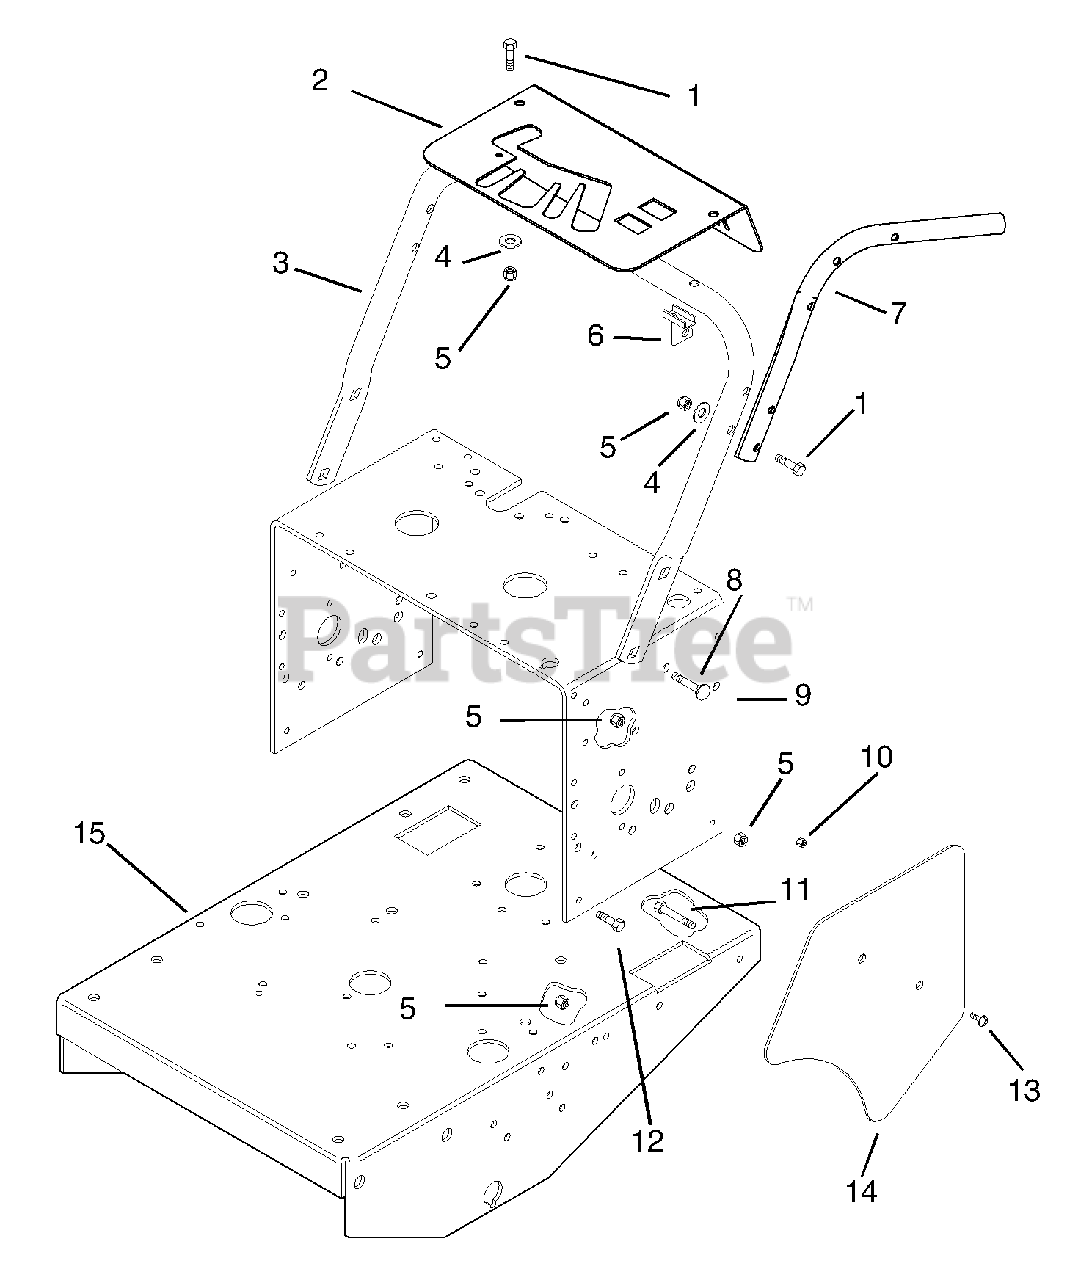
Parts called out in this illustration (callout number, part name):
1	Bolt-Hex .38-16 x 2.00 Grade 5
2	Panel, Instrument
2	Plate, Instrument
3	Tube, Handlebar Mounting
4	Washer-Flat-Steel .406 x .812 x .065
5	Nut-Locking-Nylon .375-16
6	Weldment, PTO Lever Mounting
7	Handlebar Left Hand
7	Handlebar Right Hand
8	Bolt-Round Head Square Neck .38-16 x 1.0
9	Support, Handlebar
10	Nut-Locking-Center .250-20
11	Bolt-Hex .38-16 x 1.25
12	Bolt-Hex .38-16 x 1.00 Grade 5
13	Screw-Machine .25-20 x .75
14	Guard, Belt
15	Weldment, Pro Frame
